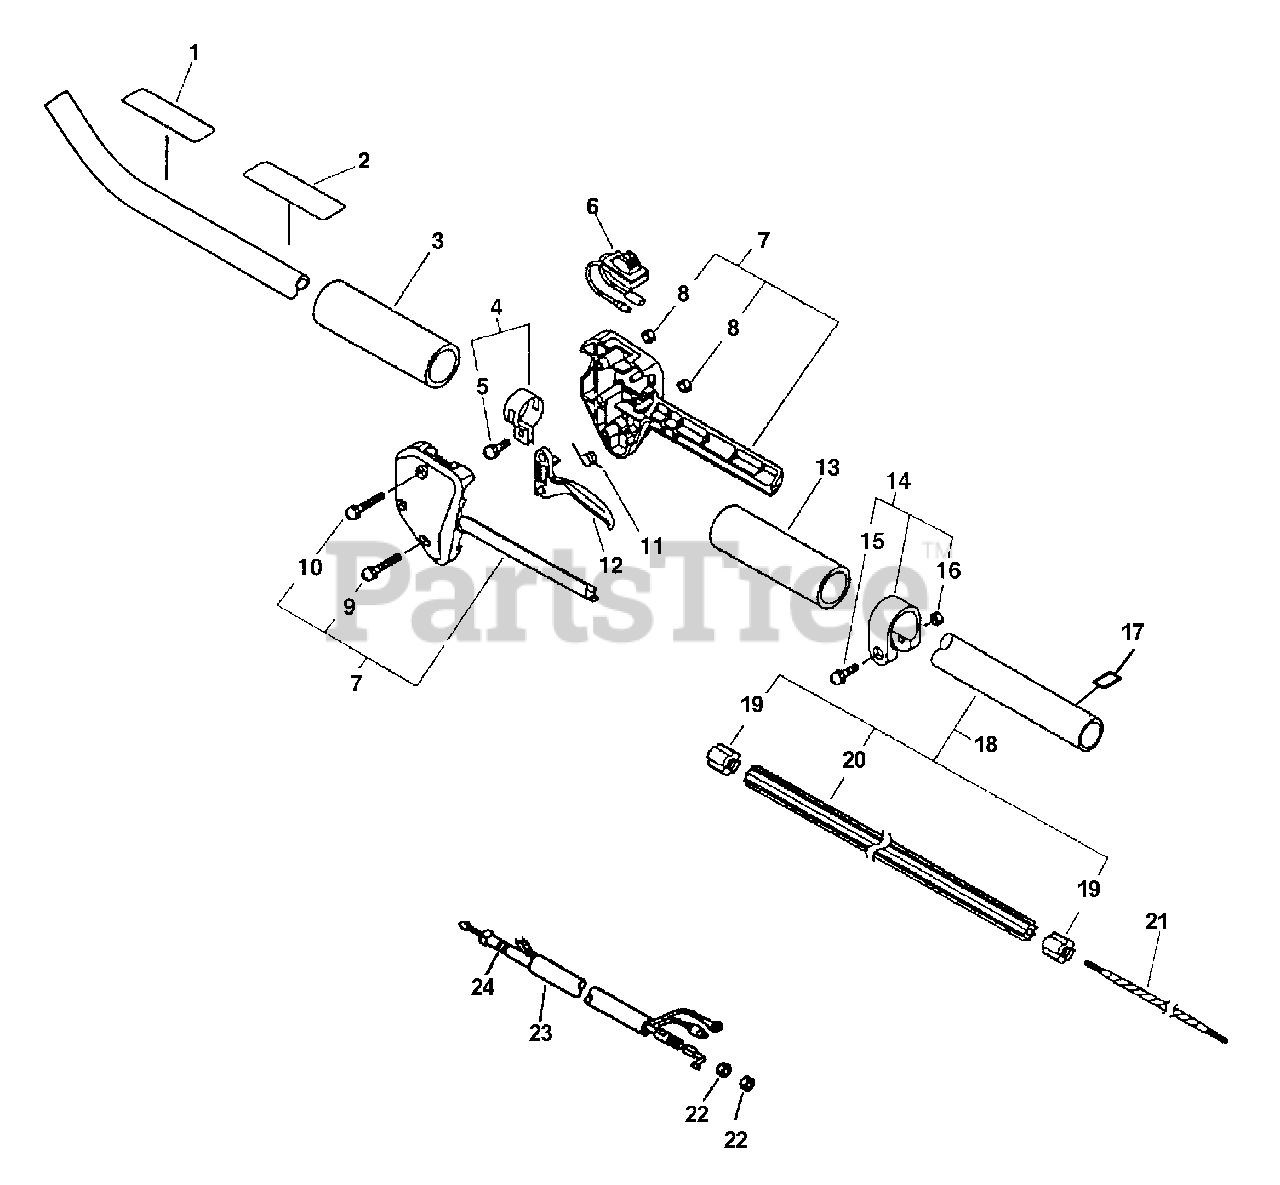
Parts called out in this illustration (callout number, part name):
1	LABEL, CAUTION
2	LABEL - CAUTION
3	GRIP, HANDLE
4	CLAMP KIT
5	SCREW 5×12
6	SWITCH ASSY, ON-OFF
7	HANDLE KIT, CONTROL
8	NUT M5
9	SCREW 5×25
10	SCREW 5×35
11	SPRING, TORSION
12	TRIGGER, THROTTLE
13	GRIP, HANDLE
14	CLAMP KIT
15	SCREW 5×28
16	NUT M5
17	LABEL - CAUTION
18	MAIN PIPE ASSY
20	LINER - FLEXIBLE
21	DRIVESHAFT - FLEXIBLE
23	TUBE
24	CABLE, THROTTLE
